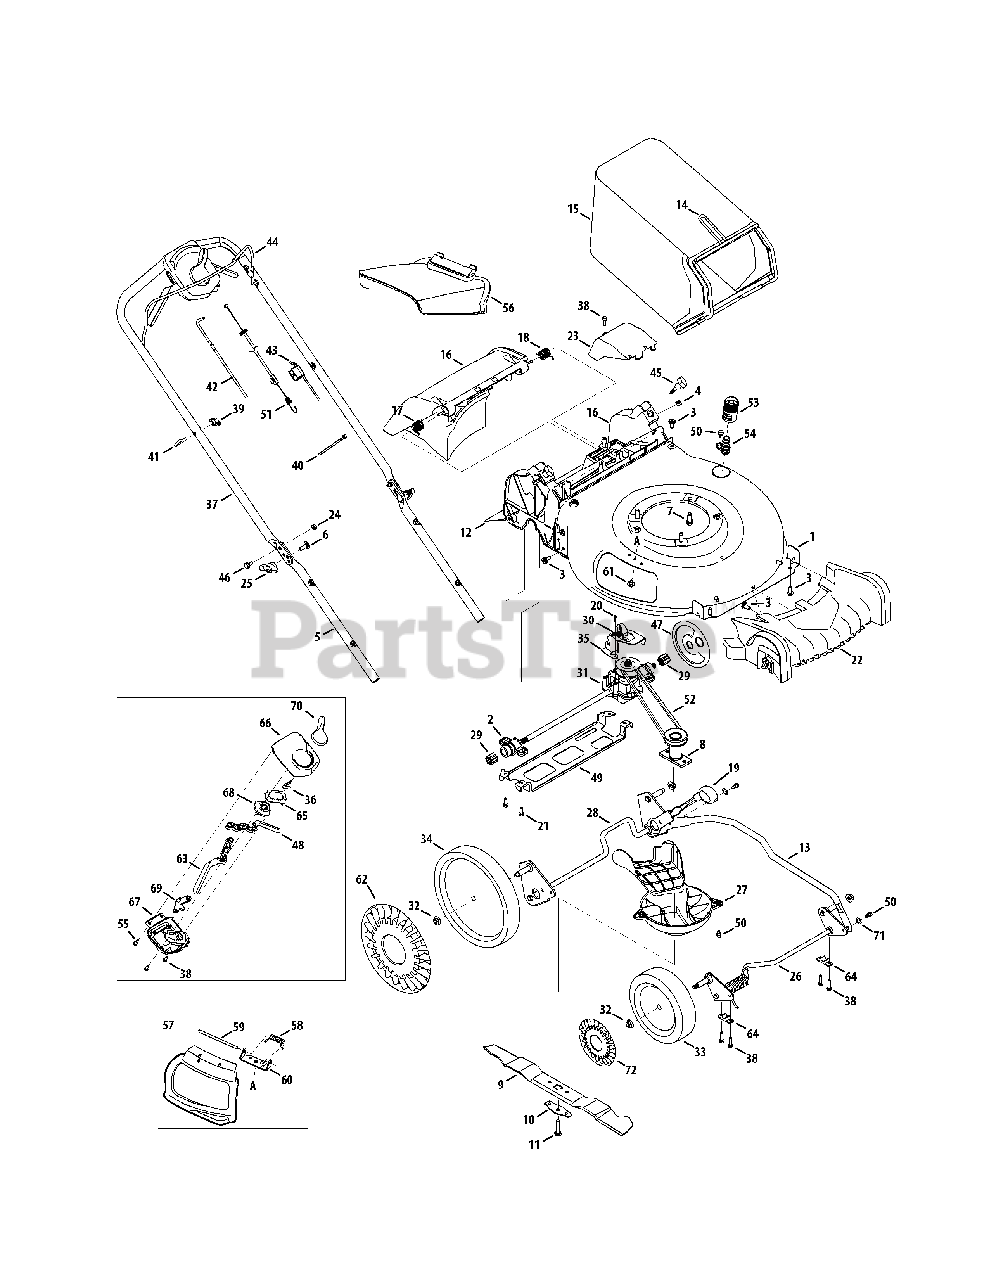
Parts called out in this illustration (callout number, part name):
1	21" Deck Ass’y
2	Bearing Assembly
3	Hex Hd. Cap Scr. 5/16-14 x .75
4	Sq. Nut 1/4-20
5	Lower Handle
6	Carriage Bolt 5/16-18
7	Hex Wash HD Tap Scr 3/8-16 x 1.0
8	Blade Adapter
9	21" Mulching Blade
10	Blade Bell Support
11	Hex Bolt 3/8-24 x 1.5" Lg. (Gr 8)
12	Trailing Shield 4.54 x 17.37
13	Cross Bracket
14	Catcher Frame
15	Grasscatcher Bag
16	Rear Baffle Ass’y (Incl. door)
17	RH Torsion Spring
18	LH Torsion Spring
19	Knob (Black)
20	Sems TT Scr. 1/4-20 x .50
21	Screw 1/4-15 x 1.25
22	Front Axle Cover
23	Transmission Cover
24	Flanged Lock Nut 1/4-20 Gr. F Nylon
25	Wing Knob-Black
26	Front Axle Ass’y
27	Engine Baffle
28	Rear Axle Ass’y
29	Spur Gear 9T
30	Extension Spring 2.405
31	Transmission Ass’y
32	Flange Locknut 3/8-16 Gr. F Nylon
33	Front Wheel
34	Rear Wheel
35	Transmission Bracket
36	Spring
37	Upper Handle - Black
38	Screw, 1/4-15 x .750
39	Knob 1/4-20
40	Cable Tie
41	Rope Guide Bolt
42	Drive Cable
43	Control Cable (Honda)
44	Blade Control (Black)
45	Knob 1/4-20 x 1.73 Black
46	Shoulder Screw .375 x .126 x 1/4-20
47	Dust Cover
48	Control Lever LH
49	Rear Support Bracket
50	Shoulder Scr. 1/4-20 x .50
51	Speed Adjustment Cable
52	V Belt
53	Water Nozzle Adapter
54	Deck Water Nozzle
55	Shoulder Screw 1/4-15 x .970
56	Chute Deflector
57	Mulching Plug Ass’y (Incl. ref. no. 58-60)
58	Torsion Spring
59	Hinge Pin
60	Chute Deflector Bracket
61	Screw 1/4-20 x .50
62	Hub Cap - 11"
63	Control Lever RH
64	Bushing .505 Dia. x .62
65	Cable Adjust Plate
66	Upper Housing
67	Lower Housing
68	Speed Adjust Actuator
69	Drive Cable Actuator
70	Speed Select Lever
71	Wave Washer
72	Hub Cap 8"
